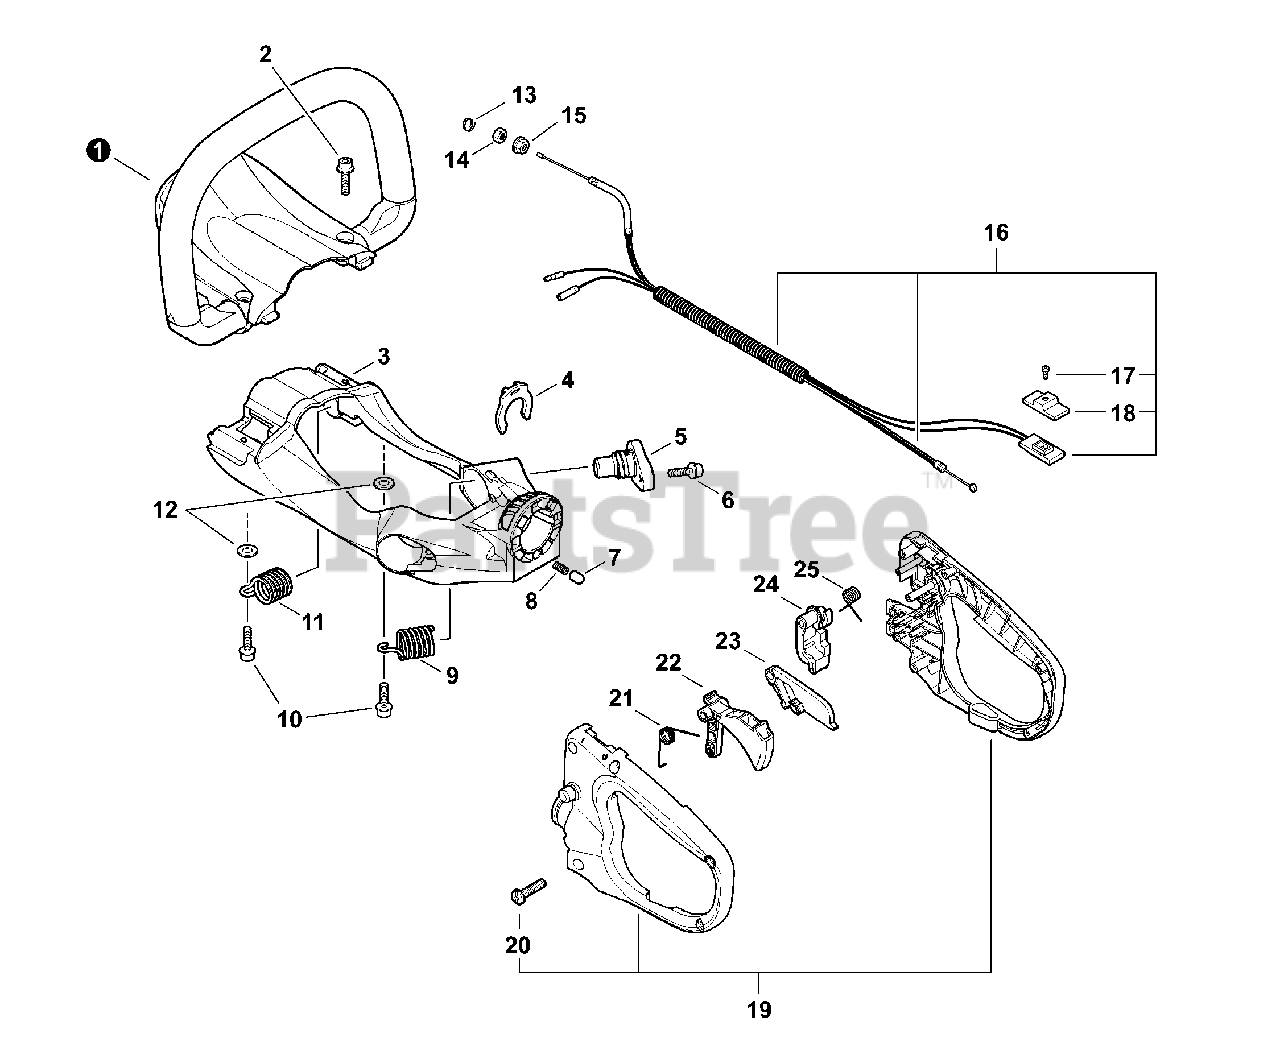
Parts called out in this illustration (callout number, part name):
1	HANDLE - FRONT
2	SCREW - 5×20
5	HOLDER, SPRING
6	SCREW - 5×20
10	SCREW - 5×16
12	WASHER - 5
15	NUT - 6 -- FLANGE
16	CONTROL CABLE ASSY
17	SCREW - 3×10
18	KNOB, SWITCH - ORANGE
19	REAR HANDLE SET
20	SCREW - 4×16
22	TRIGGER, THROTTLE
23	LOCKOUT, THROTTLE
24	LOCK, HANDLE
25	SPRING, HANDLE LOCK
